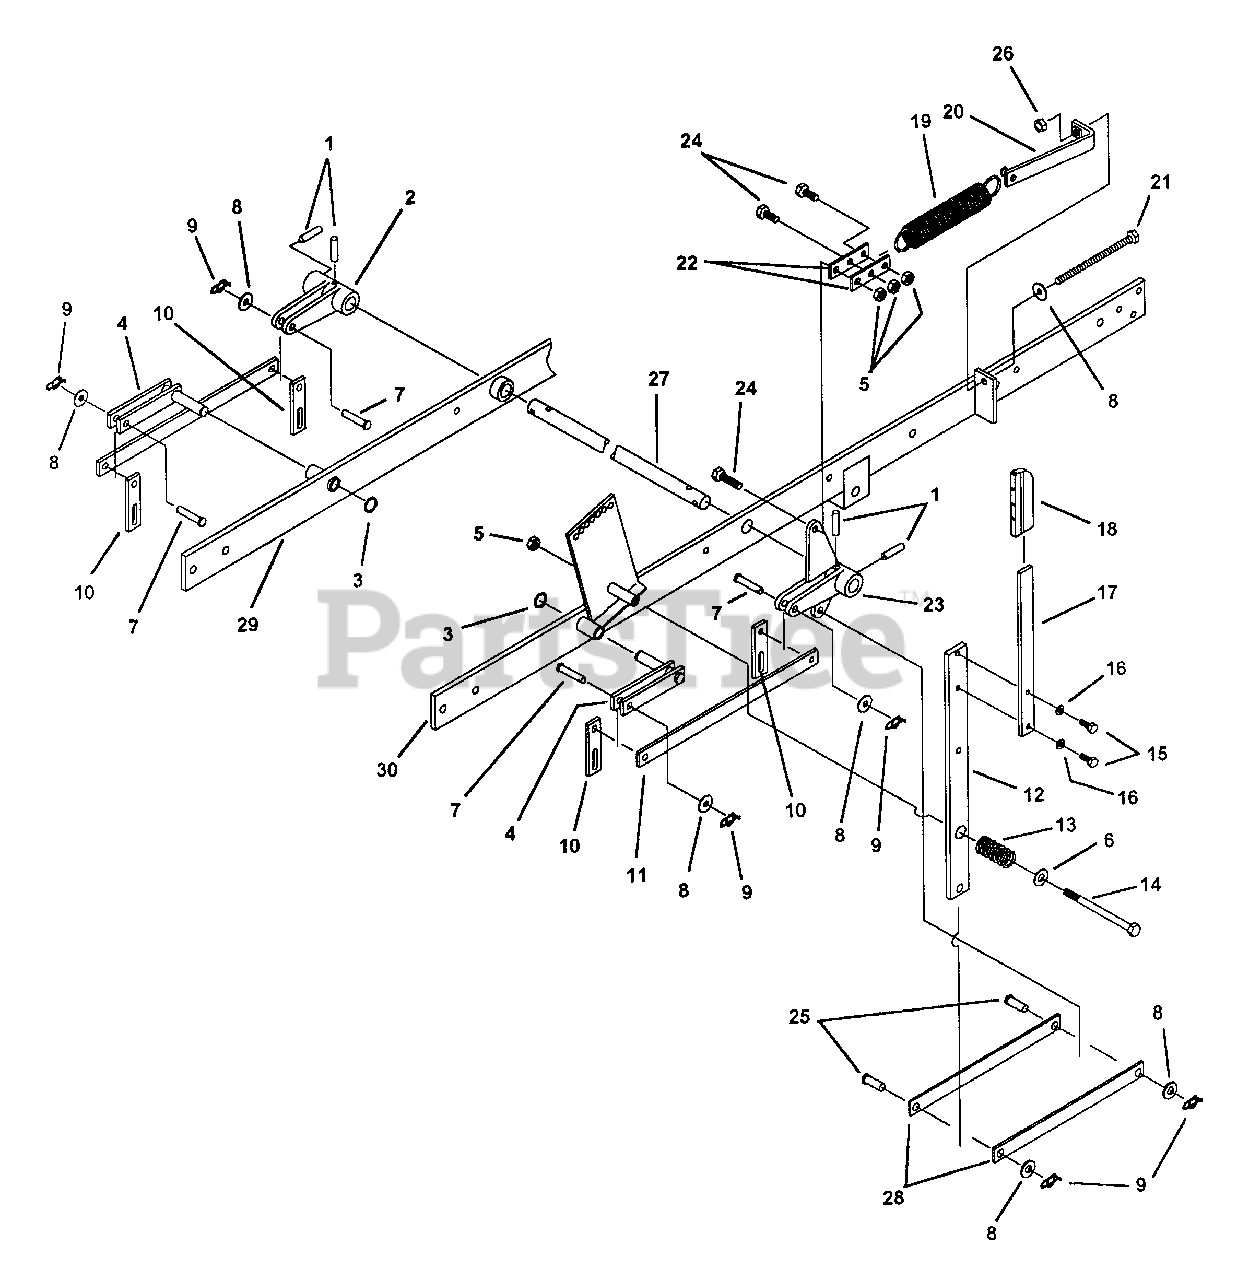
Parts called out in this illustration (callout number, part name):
1	ROLL PIN, 5/16 X 1-1/4 HBK
2	LIFT SLEEVE WELDMENT, R.H.
3	RING, 5/8" External Retaining
4	DECK HANGER WELDMENT
5	NUT, 3/8-16, NYLOC
6	WASHER, FLAT STD. 3/8"
7	CLEVIS PIN, 5/16 X 1-1/2" LONG
8	WASHER, FLAT STD. 5/16"
9	COTTER RUE RING, 5/16-3/8
10	DECK HANGER BAR
11	BAR, CONNECTING
12	LOWER HANDLE WELDMENT
13	SPRING, COMPRESSION, .975 O.D.
14	BOLT, 3/8-16 X 3" GR. 5
15	BOLT, 1/4-20 X 3/4" GR. 5
16	LOCKWASHER, 1/4" SPLIT SPRING
17	TOP DECK HANDLE
18	GRIP, HANDLE
19	SPRING, EXT., 1.65 O.D. X 9"
20	SPRING TIGHTENER WLDT.
21	BOLT, 3/8-16 X 5" FULL THREAD
22	SPRING EXTENSION
23	LIFT SLEEVE WELDMENT, L.H.
24	BOLT, 3/8-16 X 1-1/4" GR. 5
25	CLEVIS PIN, 3/8 X 1"
26	NUT, HEX. 3/8-16 UNC-2B
27	LIFT BAR
28	HANDLE LINK
29	FRAME SIDE WELDMENT, R.H.
30	FRAME SIDE WELDMENT, L.H.
